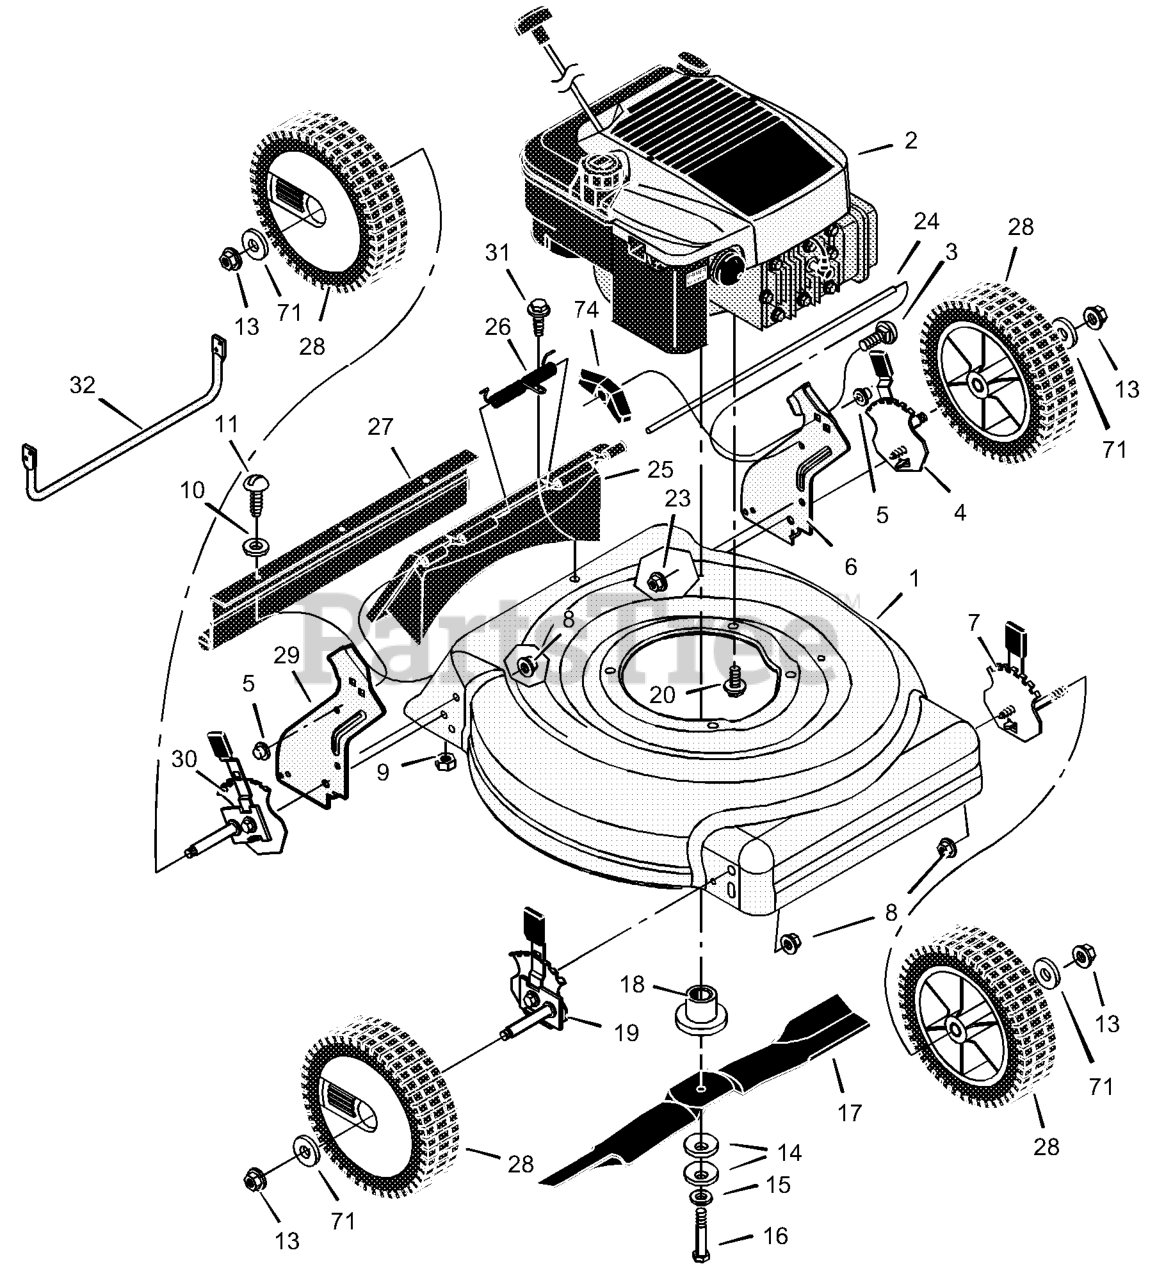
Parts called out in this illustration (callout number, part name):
1	Housing
2	Engine
3	Bolt, Carriage
4	Adjuster, Left Rear Height
5	Push On Cap
6	Bracket, Left Handle
7	Adjuster, Left Front Height
8	Nut, Flange
9	Nut, Hex
11	Screw
12	Hub Cap
13	Nut, Flange
14	Washer, Belleville
18	Adapter, Blade
19	Adjuster, Right Front Height
20	Bolt, Engine
23	Nut, Flange
24	Rod, Pivot
25	Door, Rear
27	Guard, Rear
29	Bracket, Right Handle
30	Adjuster, Right Rear Height
32	Guard, Rear
